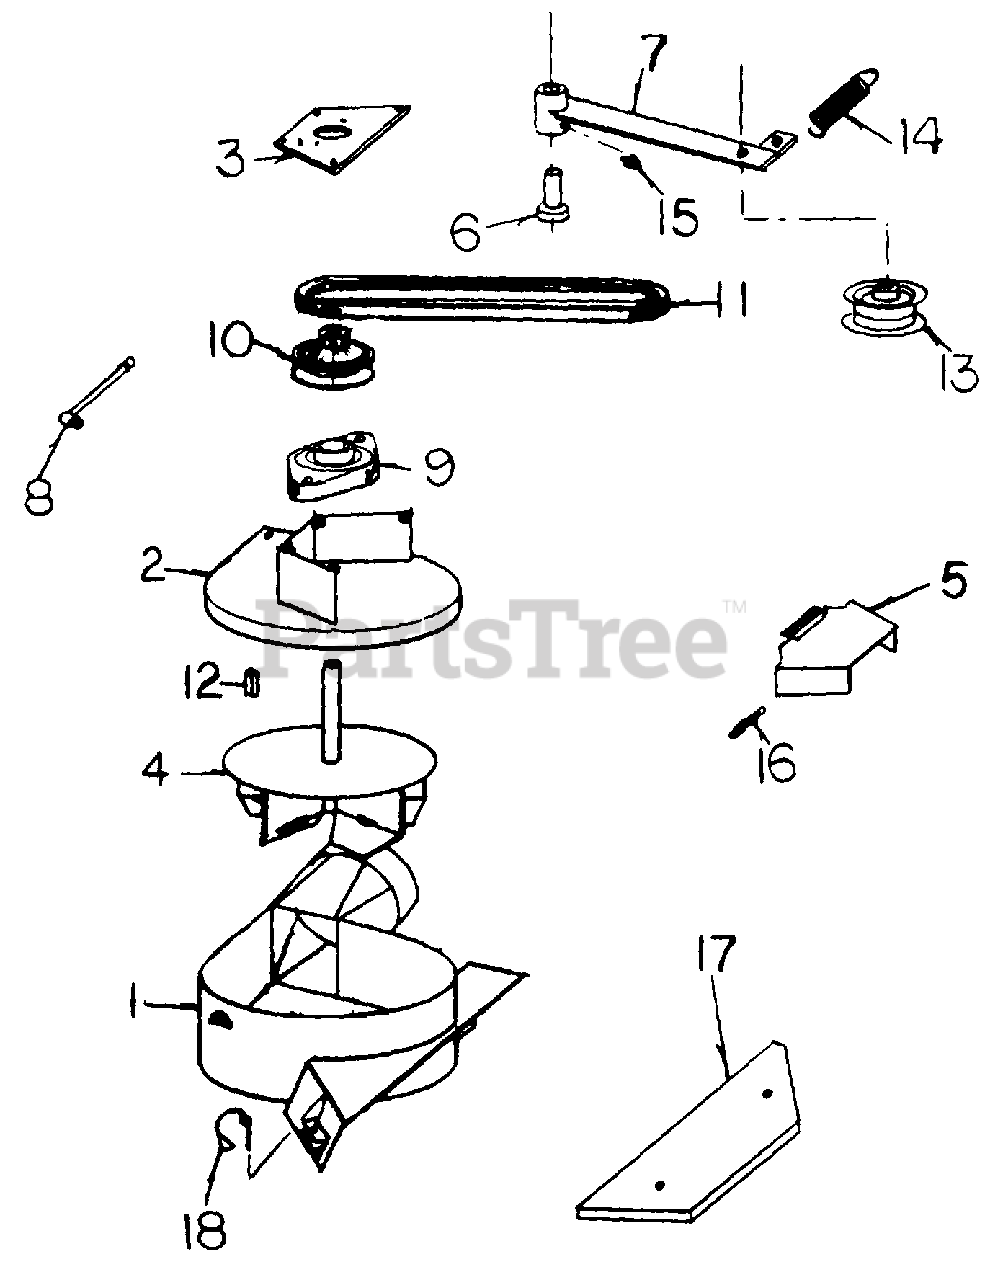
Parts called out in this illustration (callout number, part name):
1	Housing
5	Fas-tatch Belt Guard
6	Idler Arm Bushing
9	2 Bolt Flange Bearing, 3/4"
10	Pulley, Vac Blower
11	Blower Belt
12	Key, 3/16" x 3/16" x 1"
13	Idler Pulley
15	Self-tapping Zerk, 1/4-28
17	Deck Weight
